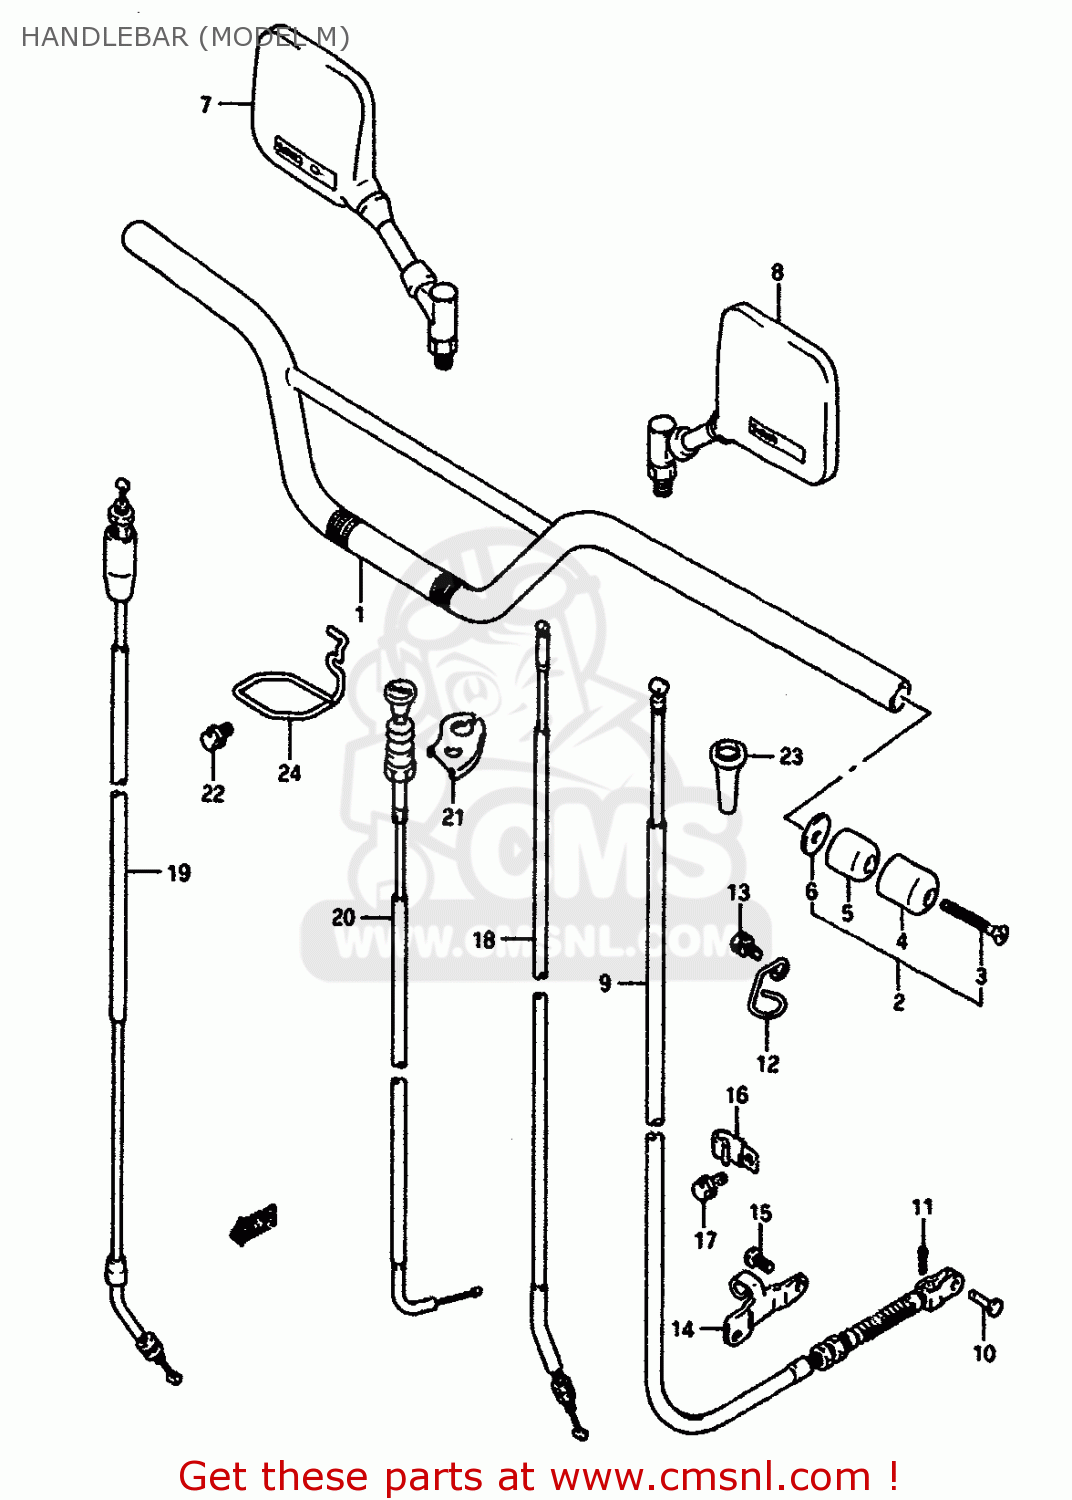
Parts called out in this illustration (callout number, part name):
1	HANDLEBAR(BLACK)
2	BALANCER SET,HANDLEBAR
3	SCREW
4	CAP,BALANCER
5	BALANCER,HANDLEBAR
6	SPACER,BALANCER
7	MIRROR ASSEMBLY,REAR VIEW
8	MIRROR ASSEMBLY,REAR VIEW
9	CABLE ASSY,CLUTCH
10	PIN(L:13)
11	PIN
12	GUIDE
13	BOLT ,6X12
14	STOPPER,CLUTCH CABLE
15	SCREW
16	CLAMP
17	BOLT
18	CABLE ASSY,DECOMP
19	CABLE ASSY,THROTTLE
20	CABLE ASSY,STARTER
21	BRACKET,STARTER CABLE
22	BOLT
23	BOOT,CLUTCH CABLE
24	GUIDE,CABLE
